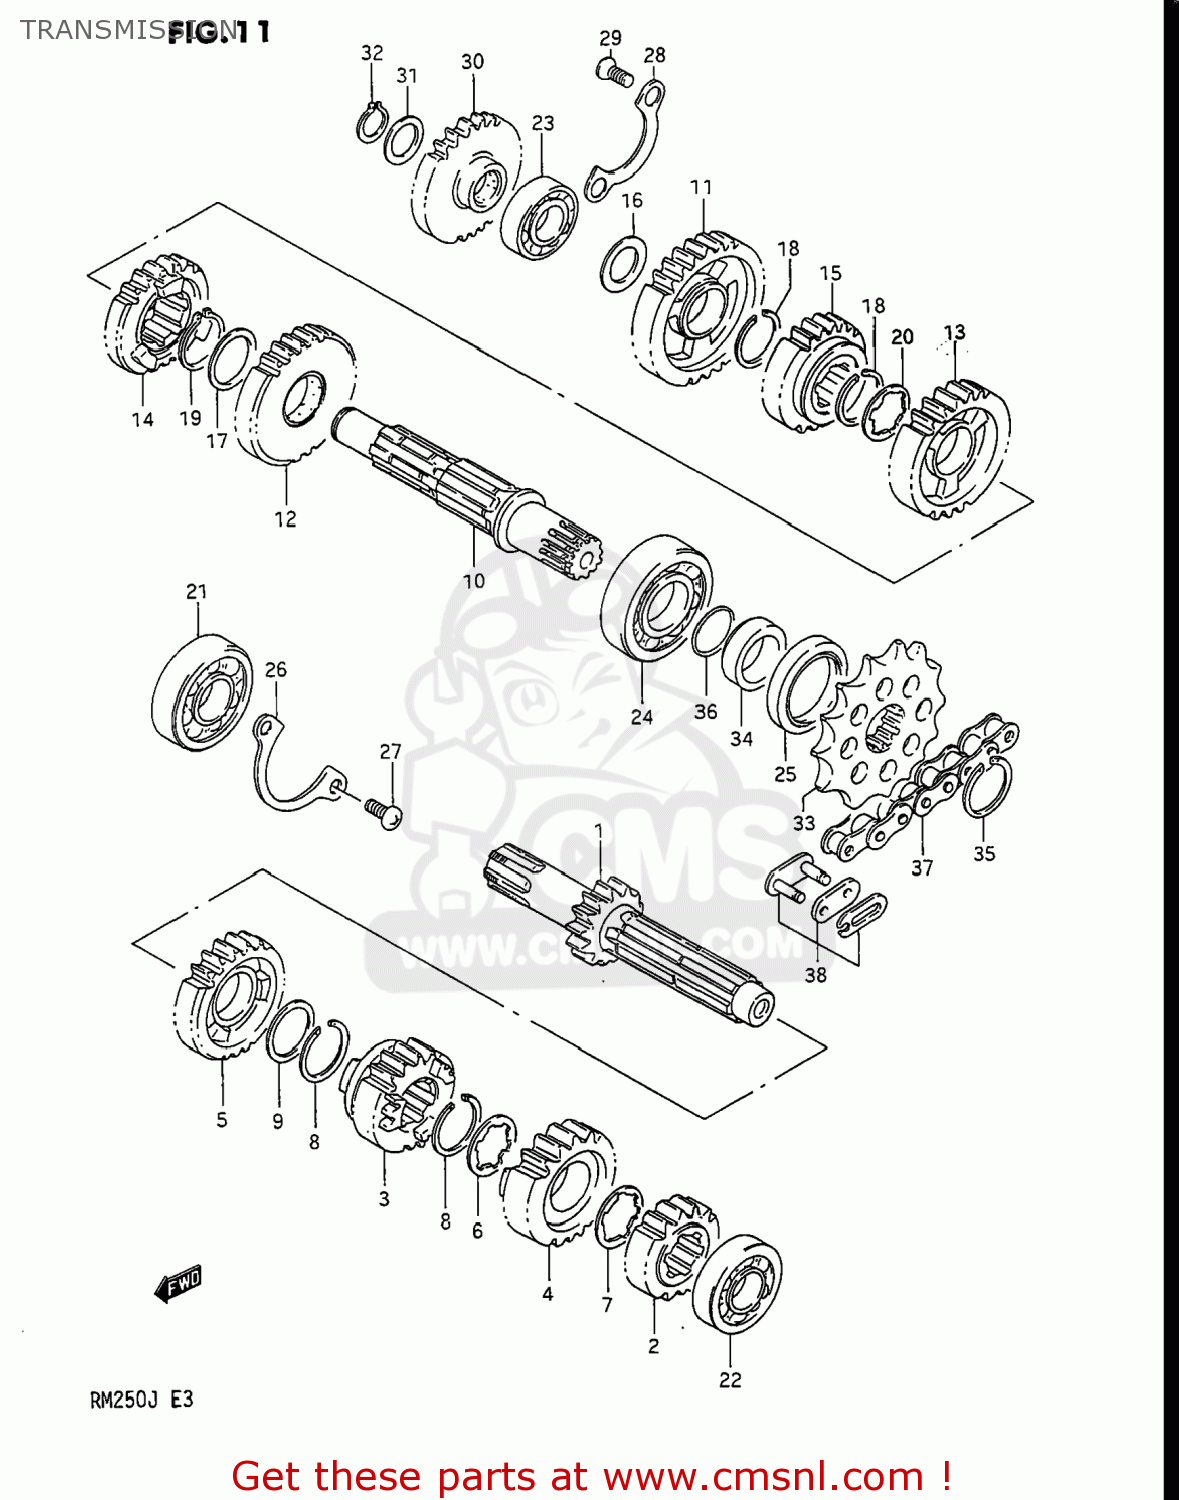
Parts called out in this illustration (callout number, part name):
1	SHAFT,COUNTER
2	GEAR,2ND DRIVE
3	GEAR,THIRD DRIVE
4	GEAR,FOURTH DRIVE
5	GEAR,5TH DRIVE
6	WASHER,LOCK
7	WASHER,LOCK
8	CIRCLIP
9	SHIM(22X28X0.5)
10	SHAFT,DRIVE
11	GEAR,FIRST DRIVEN
12	GEAR,SECOND DRIVEN
13	GEAR,THIRD DRIVEN
14	GEAR,FOURTH DRIVEN
15	GEAR,FIFTH DRIVEN
16	WASHER
17	SHIM
18	CIRCLIP
19	CIRCLIP,25MM
20	WASHER,LOCK
21	BEARING(20X52X15)
22	BEARING(17X40X12)
23	BEARING(17X40X12)
24	BEARING
25	SEAL,OIL(32X42X6)
26	PLATE,COUNTERSHAFT BEARING
27	SCREW 6X12
28	PLATE,DRIVESHAFT BEARING
29	SCREW
30	GEAR,KICK STARTER IDLE
31	WASHER
32	CIRCLIP
33	SPROCKET,ENGINE
34	SPACER(22X32X9.5)
35	CIRCLIP
36	O RING(D:1.7,ID:22)
37	CHAIN ASSEMBLY,DRIVE
38	JOINT ASSEMBLY,CHAIN
